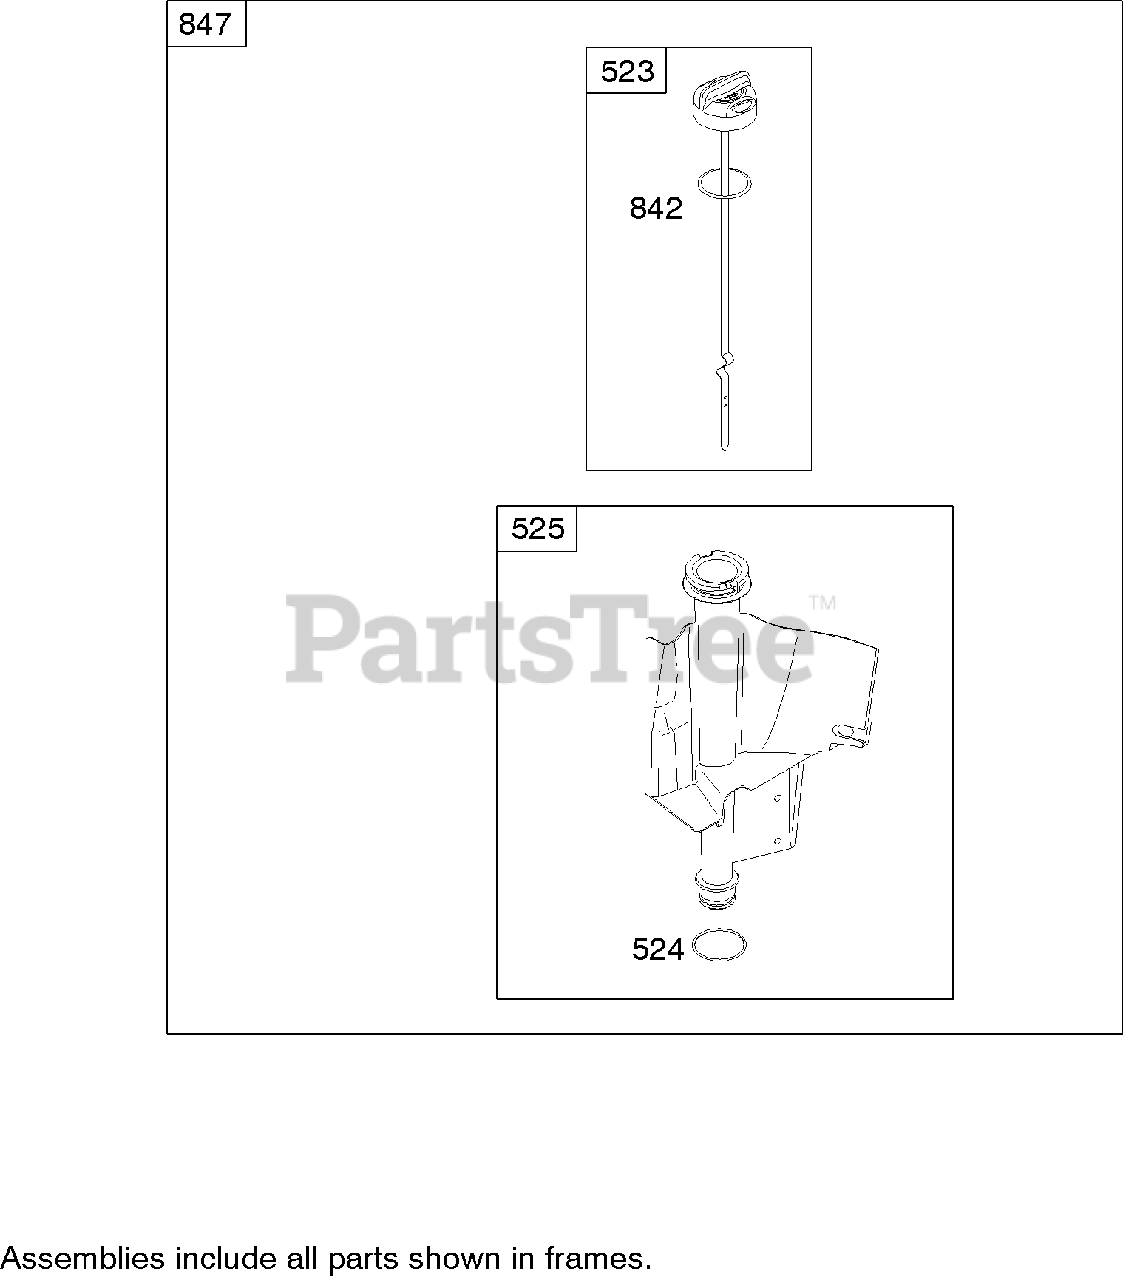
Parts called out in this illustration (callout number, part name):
523	Dipstick
524	Seal-O Ring
525	Tube-Dipstick
842	Seal-O Ring
847	Dipstick and Tube ASM
